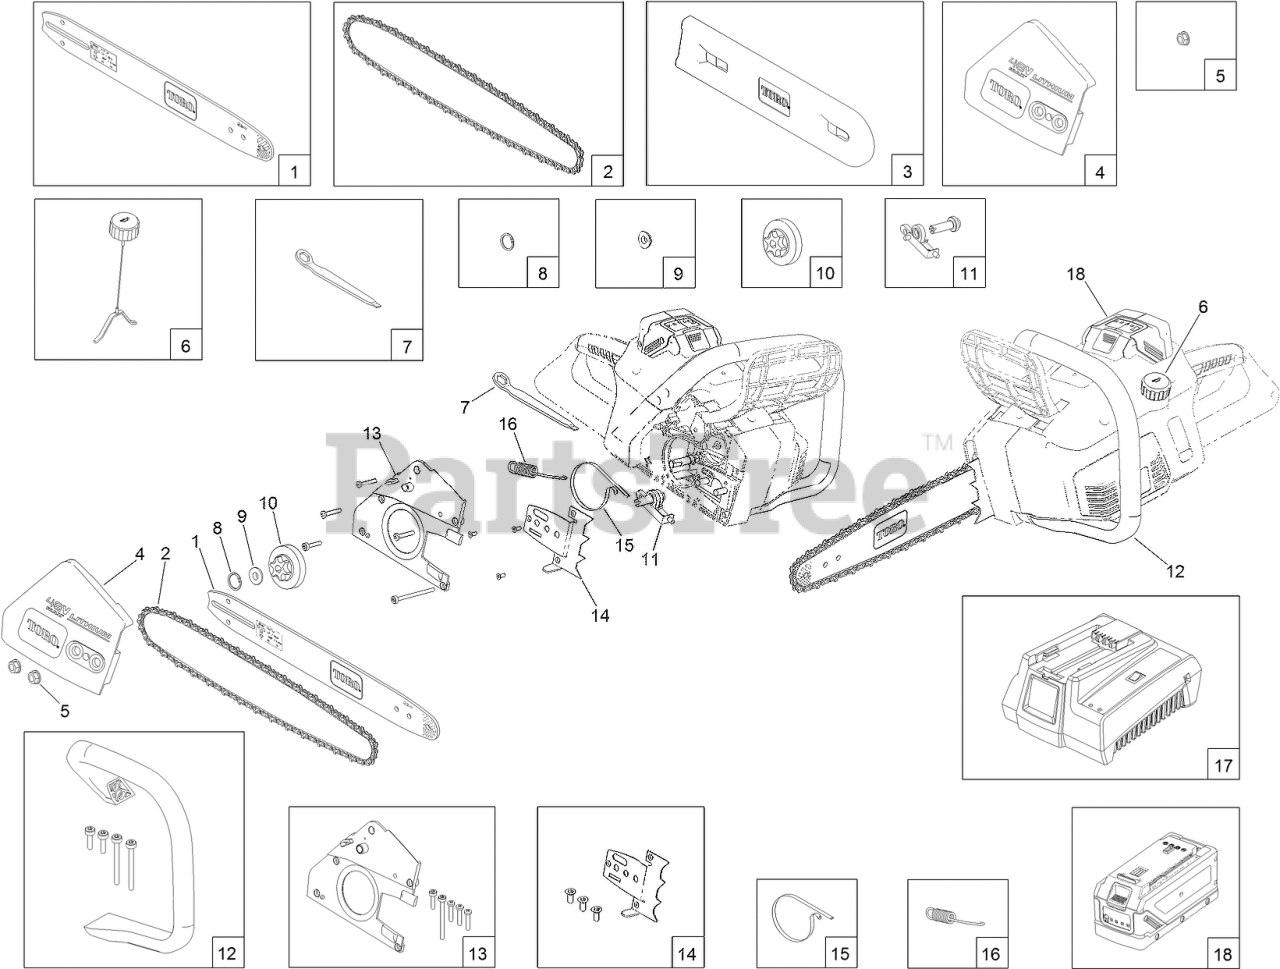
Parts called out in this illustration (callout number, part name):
1	BAR-REPLACEMENT
2	CHAIN-REPLACEMENT
3	SLEEVE-BAR
4	COVER-BAR/CHAIN
5	NUT-M8
6	OIL CAP ASM
7	WRENCH
8	SNAP-RING
9	SPACER
10	SPROCKET
11	BAR AND CHAIN ADJUSTER ASM
12	HANDLE ASM
13	INTERNAL COVER ASM
14	BUCKING TEETH BRACKET ASM
15	BRAKE-BAN
16	SPRING-LEVER, BRAKE
17	CHARGER-REPLACEMENT, 48V
18	BATTERY-REPLACEMENT, 48V
